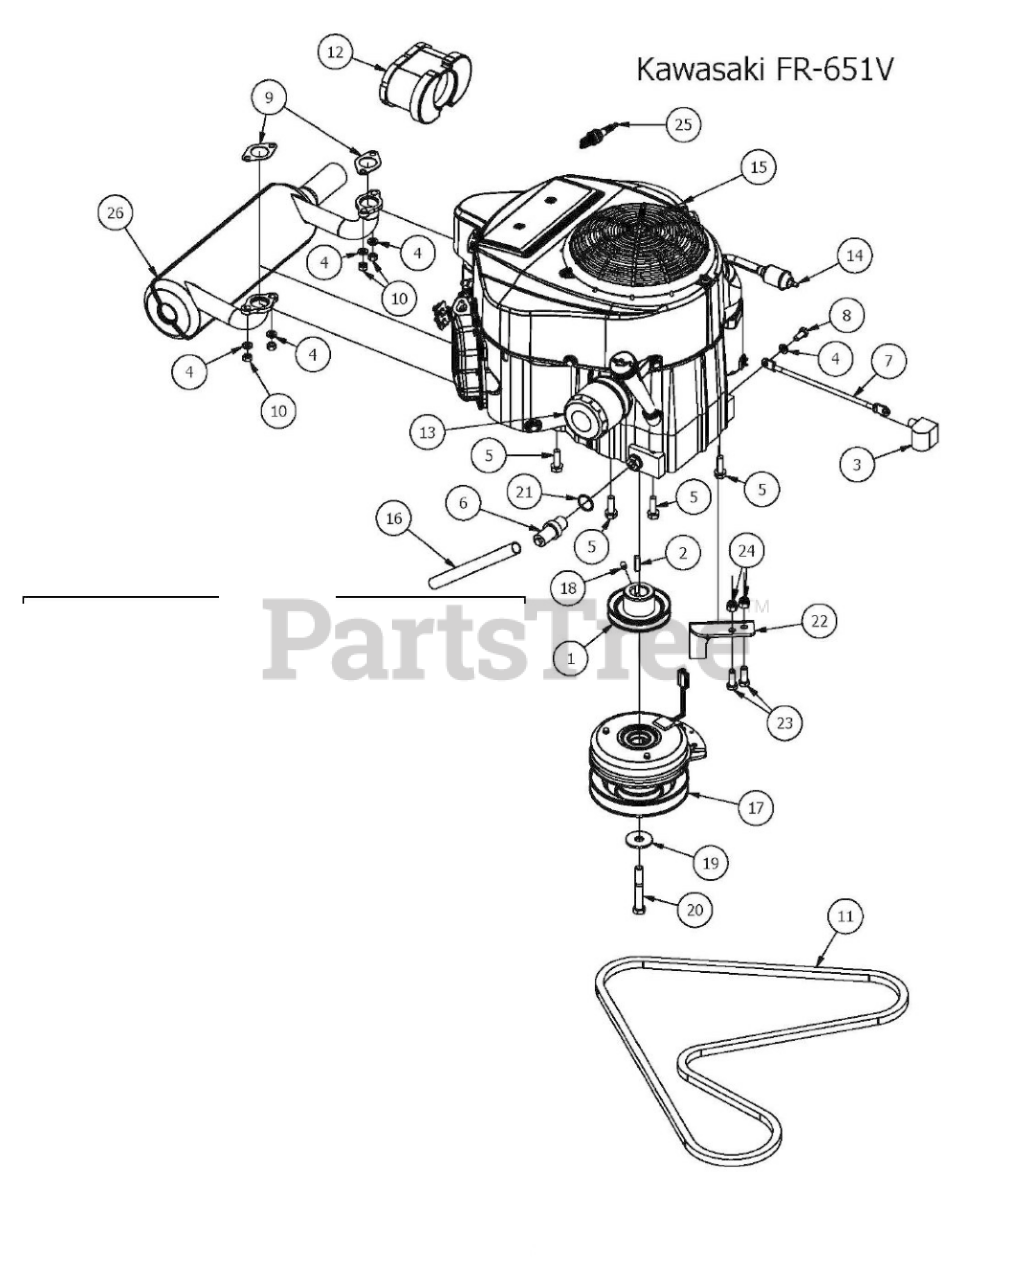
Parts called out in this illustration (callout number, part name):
1	3-3/4" Motor Pulley
2	1/4" x 1" Key
3	Black Boot For Ground Cable
4	5/16" Lock Washer
5	3/8 x 1 1/8 bolt
7	Ground Cable
8	M8x1.20x20MM Hex head bolt
9	Exhaust Gasket
10	M8-1.25 Zinc Nut
12	Kawasaki Air Filter
13	Kawasaki Oil Filter
14	Universal Inline Fuel Filter
15	726cc Kawasaki Engine-FR651V
16	1/2 Clear Braded Hose Priced/Foot
17	Clutch 2017 Magnum/MZ
18	3/8" Set Screw
19	1/2 Belleville Washer
20	7/16"-20 x 3" Hex Bolt Gr. 8
22	2017 MZ Clutch Stop
23	3/8" x 1" Hex Bolt
24	3/8 Nylock Nut
25	Spark Plug- Kawasaki
26	Kawasaki Muffler 1251
